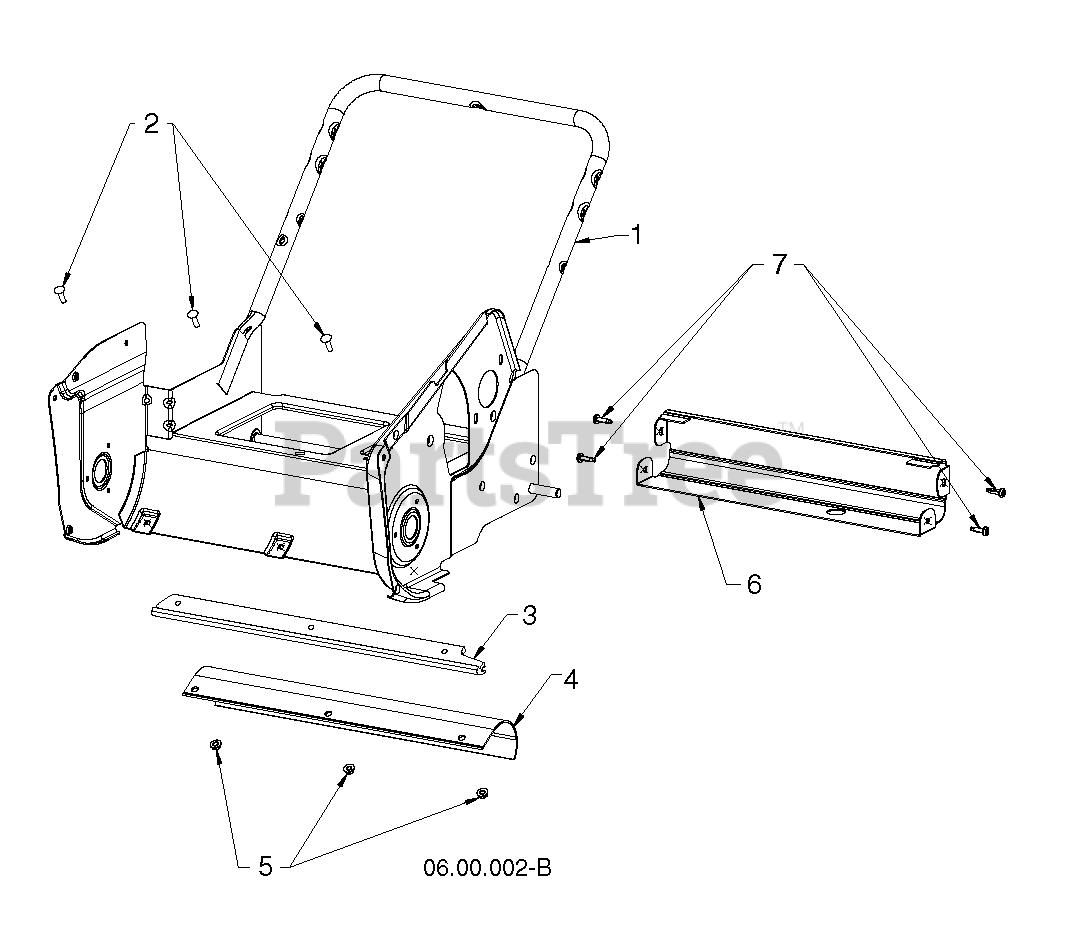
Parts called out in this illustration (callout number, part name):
1	FRAME.WELDMENT.GREY
2	BOLT.CARRIAGE.1/4-20 X 7/8
3	BAR.SCRAPER.SINGLE.STAGE.GREY
4	SKIRT.SCRAPPER-SSST
5	NUT.HEX.FLANGE.1/4
6	SUPPORT.SSST.REAR.FRAME.GREY
7	SCREW.PAN.HD.TORX.1/4-20X.750
